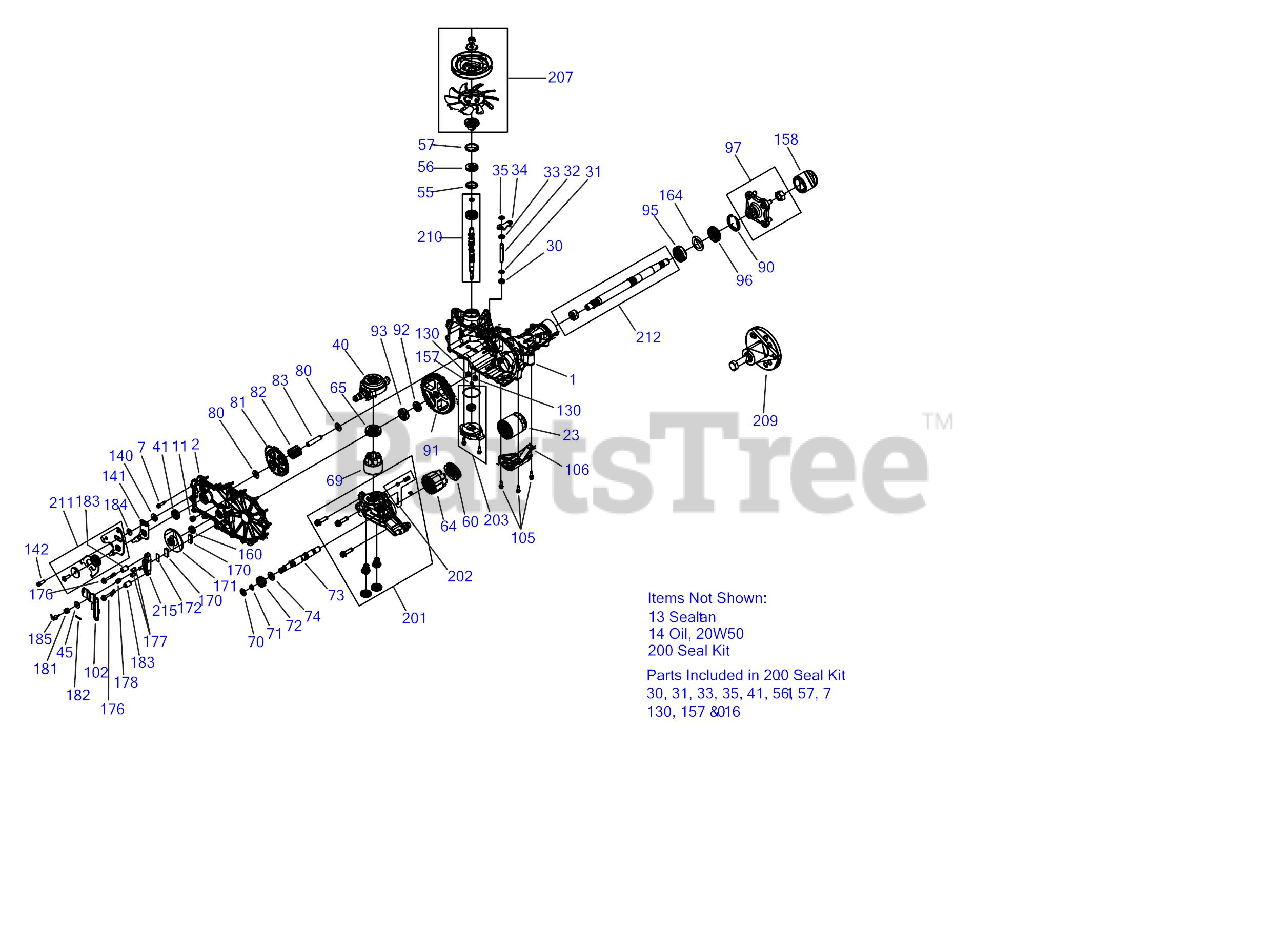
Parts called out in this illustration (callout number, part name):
1	Kit, Main Housing, RH Charge
2	Kit, Cover Side RH Control
7	Screw, Hex Washer
23	Filter, Spin-On 2.6 x 3.0
30	Seal, Lip, .375 x .75 x .25
31	Ring, Retaining .375 External
32	Rod, Bypass
33	Ring Retaining .750 Internal
34	Arm, Bypass
35	Ring, Ret .375 External
40	Trunnion, Swashplate
41	Seal, Lip 18 x 32 x 7
45	Washer, .34 x .88 x .06
55	Washer, 1.23 x 1.57 x .04
56	Seal, Lip 17 x 40 x 7
57	Ring Retaining Internal
60	Bearing, Thrust 35 x 62 x 18
64	Kit, 16cc Cylinder Block Assembly
65	Thrust Bearing, 30 x 52 x 13
69	Kit, Block, 7 Piston
70	Washer, .63 x 1.00 x .05
71	Ring, Reatining, Motor Shaft
72	Gear, 14T (Steel)
73	Shaft, Motor
74	Washer, .71 x 1.16 x .04
81	Gear, 45T
82	Gear, 11T (Steel)
83	Pin, Jackshaft
90	Ring, Retaining 2.25 Internal
91	Gear, 54T
92	Spacer, .750 x 1.00 x .257
93	Bearing, Ball 3/4 x 40mm x 12mm
95	Bearing, Ball 25.4 x 52 x 15
96	Seal, Lip, 1.0 x 2.06 x .38
97	Kit, Hub 4-Bolt
102	Arm, Brake
105	Screw, Hex Washer 1/4-20 x .75
106	Guard, Filter, RH
130	Tube, Charge Triple O-Ring
140	Spacer, .320 x 1.005 x .150
141	Arm, Return Left
142	SHCS, 5/16-24 x 7/8 (W/Patch)
157	Seal, Gerotor .281 x .420 x .160
158	Cap, Axle
160	Seal, Lip .625 x 1.00 x .250
164	Spacer, 1.355 x 2.035 x .021
170	Puck, Brake
171	Rotor, Brake
172	Puck, Plate
176	Screw .250-20 x 2.0 HFS Patch
177	Pin, Brake Actuating
178	Compression Spring
181	Nut, Castle 5/16-24
182	Pin, Cotter 3/32 x 3/4
184	Washer, .34 x .88 x .06
185	Spring, Brake Arm Bias
200	Kit. Seal, ZT-2800
201	Kit, Center Section RH Charge
202	Kit, Charge Relief
203	Kit, Charge
207	Kit, Fan Pulley
207	Fan Only
207	Pulley Hub
209	Kit, Hub Puller
210	Kit, Input Shaft
211	Kit, RTN Bidirectional
212	Kit, Shaft Axle
215	Kit, Brake Yoke
